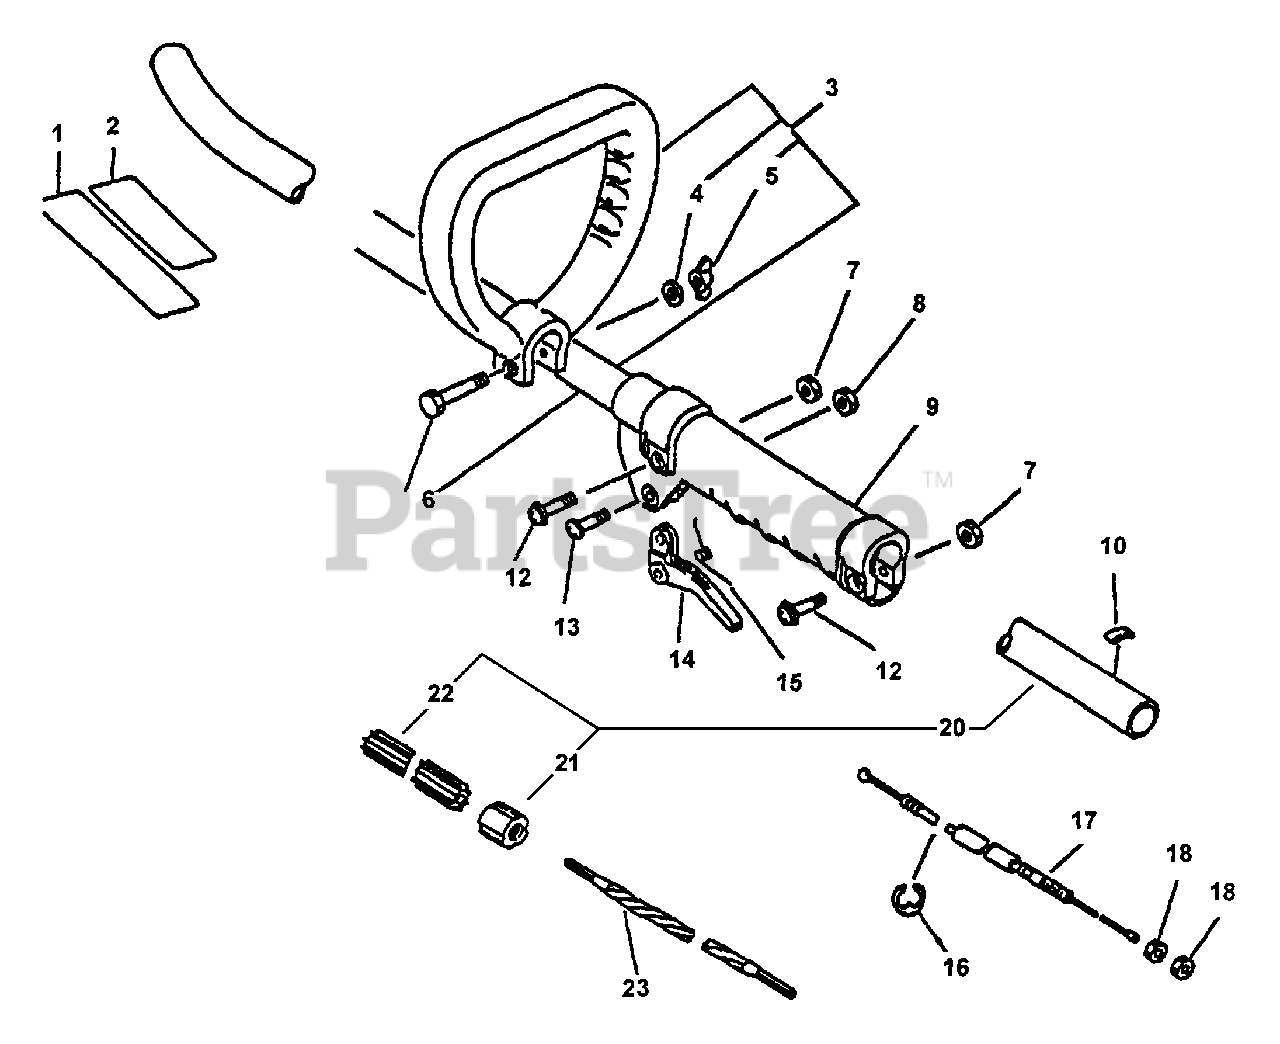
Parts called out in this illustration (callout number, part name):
1	LABEL, CAUTION
2	LABEL, CAUTION
3	HANDLE ASSY
4	WASHER, 1/4"
5	NUT, WING 1/4"-20
6	BOLT 1/4"-20×1-1/2"
7	NUT M5
8	NUT, LOCK M5
10	LABEL - ALIGNMENT
12	SCREW 5×25
14	TRIGGER, THROTTLE
15	SPRING, THROTTLE
16	RING, RETAINING - 5
17	CABLE, THROTTLE
20	MAIN PIPE ASSY
22	LINER - FLEXIBLE
23	DRIVESHAFT - FLEXIBLE L= 1522
